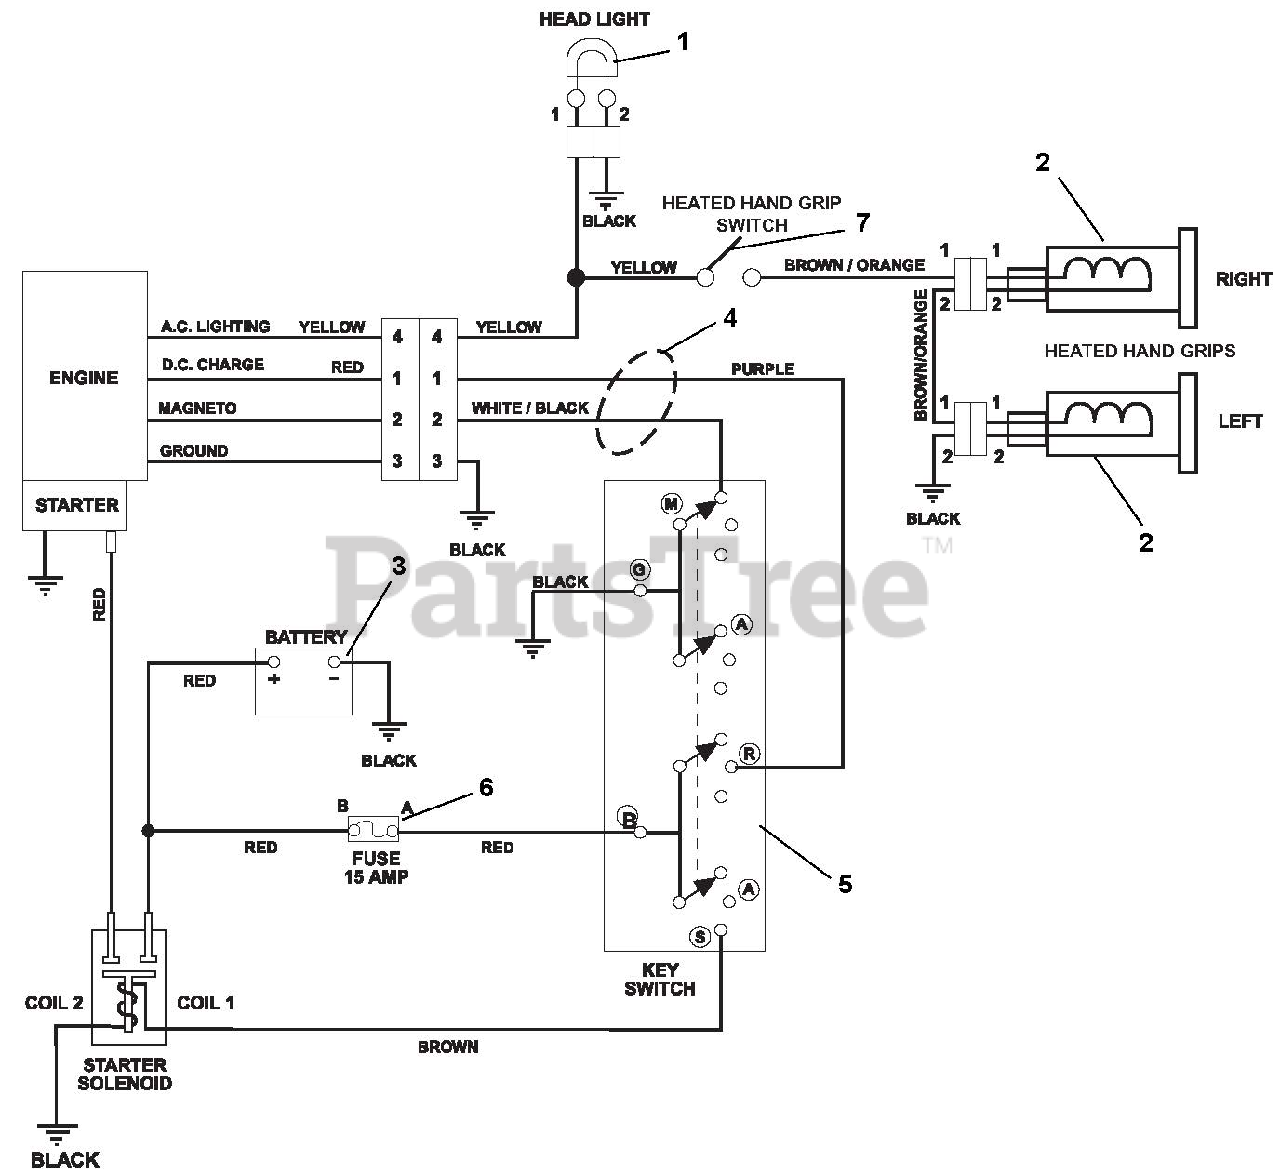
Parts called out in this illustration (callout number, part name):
1	Head Light Assembly
2	Heated Hand Grip with Terminal
3	Battery
4	Harness, Wire-12V, Light and Heated Hand Grips
5	Switch Assembly
6	15 AMP Fuse
7	Switch, On/Off Heated Hand Grips
